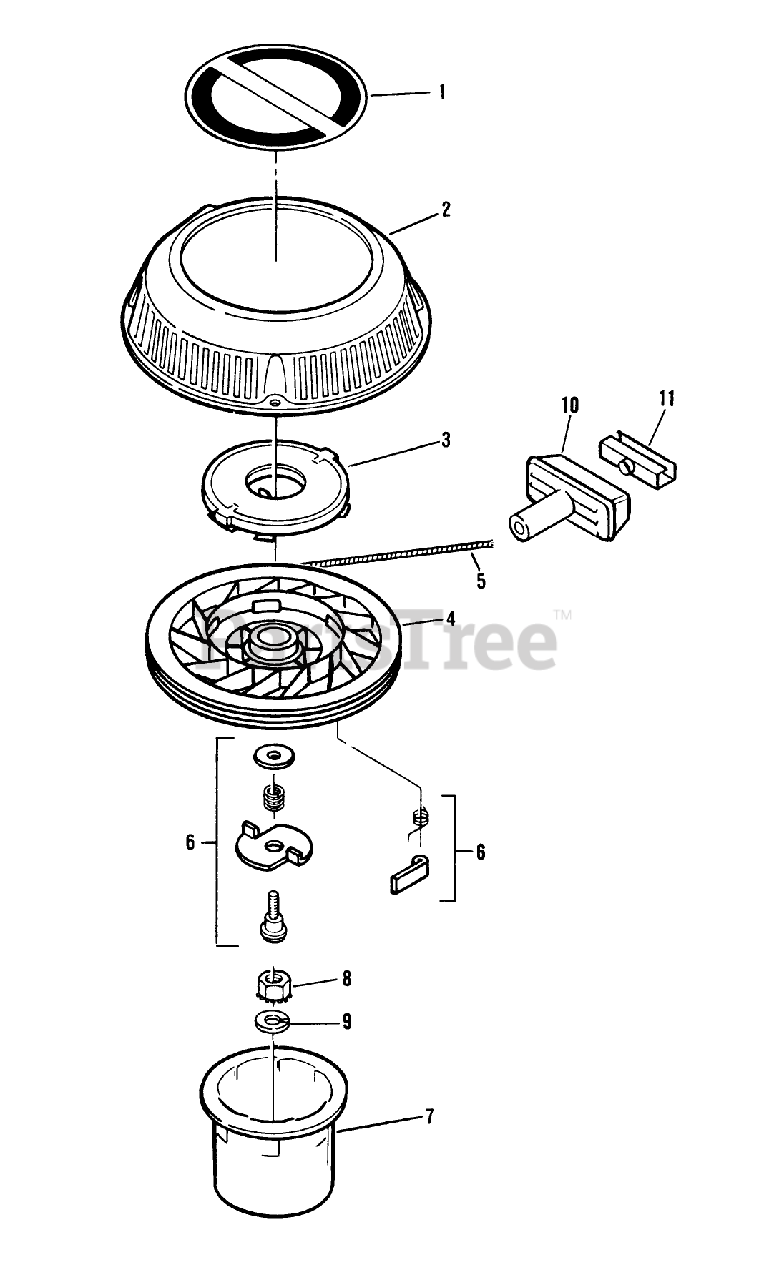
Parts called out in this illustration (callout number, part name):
4	PULLEY
6	DOG KIT
7	HUB-STARTER E COMM.
8	NUT
11	CLIP-STARTER
